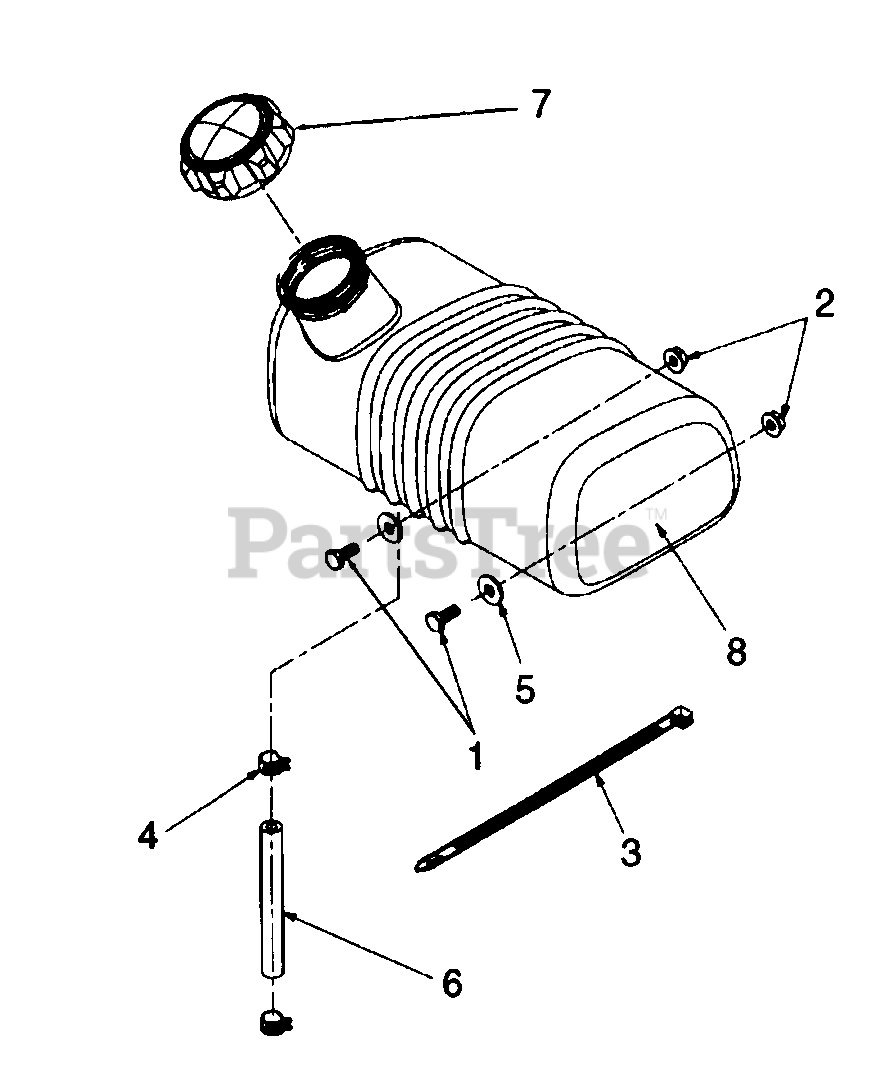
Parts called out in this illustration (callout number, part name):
1	Screw, Hex Cap, 1/4-20 x .62
2	Nut, Hex Flange Lock, 1/4-20
3	Cable Tie, 30.66 Lg
4	Clamp, Hose, 1/2 Inch
5	Washer, Flat, .28 x .74 x .063
6	Hose, Fuel Line 9 Inch
7	Cap, Fuel
8	Tank, Fuel
